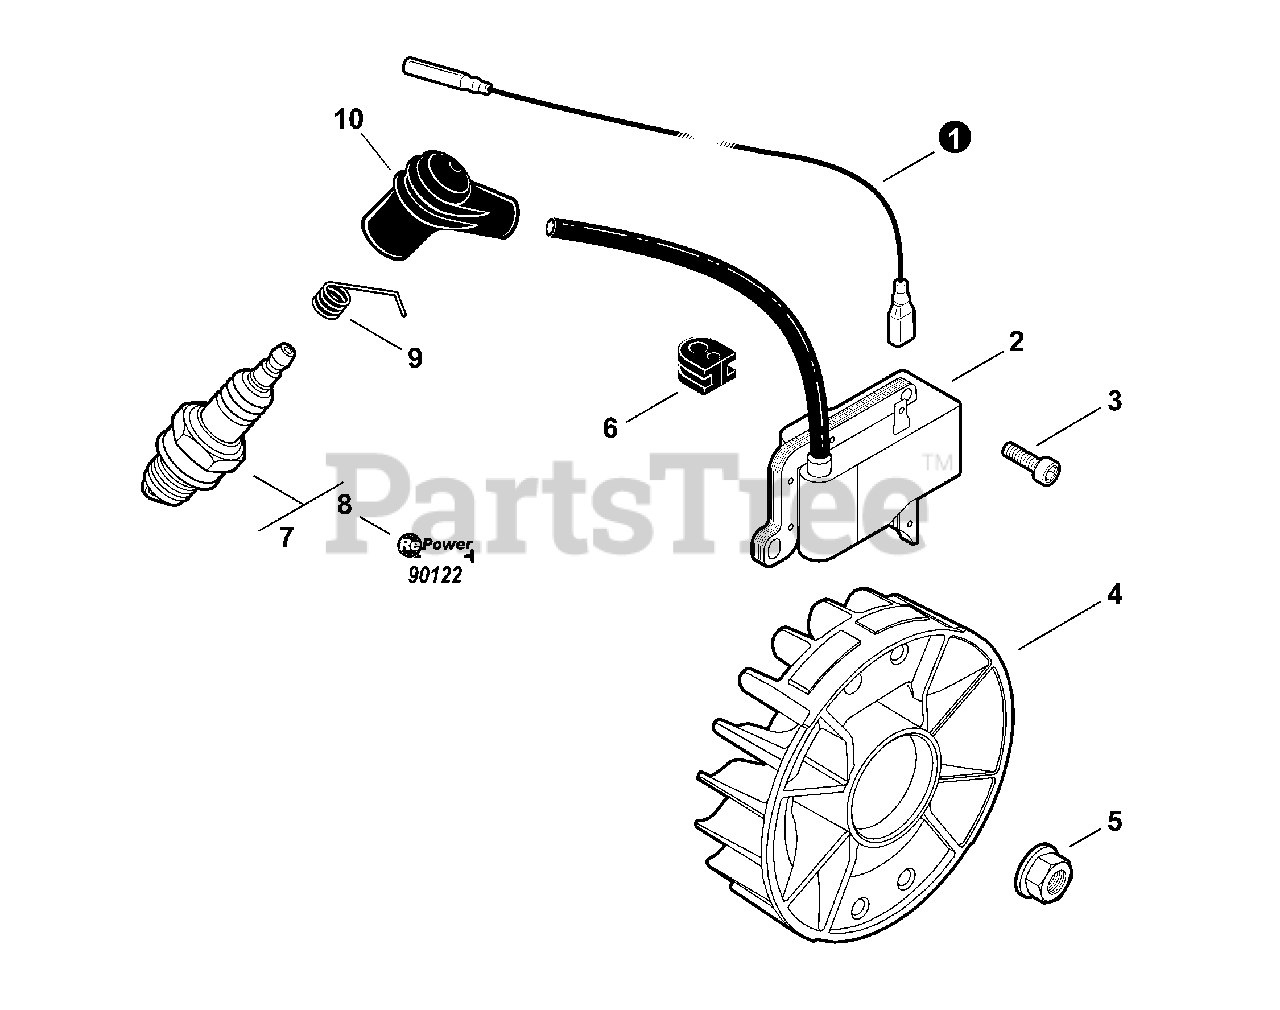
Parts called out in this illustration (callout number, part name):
1	LEAD L= 470
2	COIL, IGNITION
3	BOLT, TORX 5×20
4	FLYWHEEL
5	NUT, FLANGE 10×1.25
7	SPARK PLUG - BPM8Y
8	SPARK PLUG - BPMR8Y
9	TERMINAL, SPARK PLUG
10	CAP, SPARK PLUG
